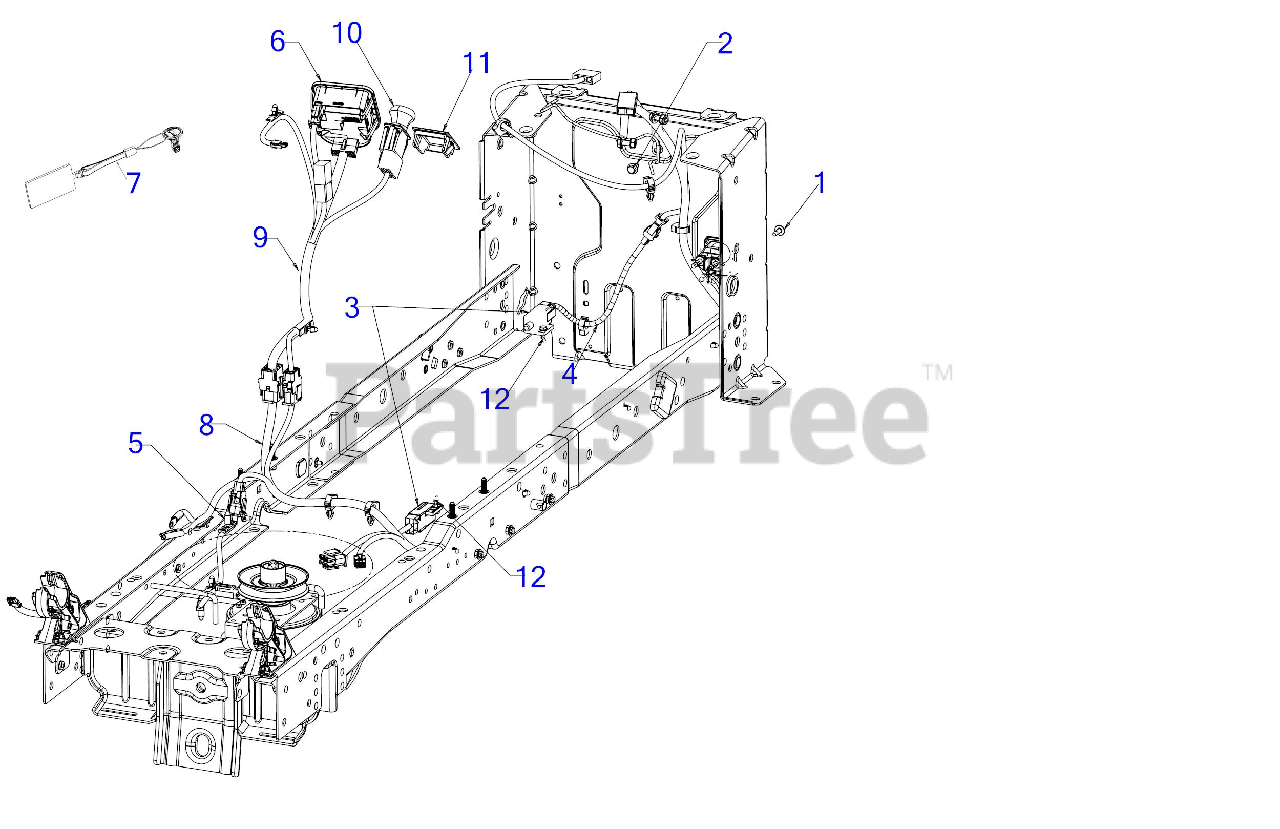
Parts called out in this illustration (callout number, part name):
1	SCREW M6-1 x .625
2	SCREW 1/4-20X.625
3	INTERLOCK SWITCH (NO/NC)
4	REVERSE HARNESS
5	CLUTCH HARNESS 11"
6	MODULE-PBS/HRMTR/SVC MNDR
7	PBS KEY
8	MAIN HARNESS (E-PTO/PBS/EFI)
9	DASH HARNESS (E-PTO/PBS/EFI)
10	PTO SWITCH (YELLOW KNOB)
11	DASH HOUR METER PLUG
12	SHOULDER SCREW
